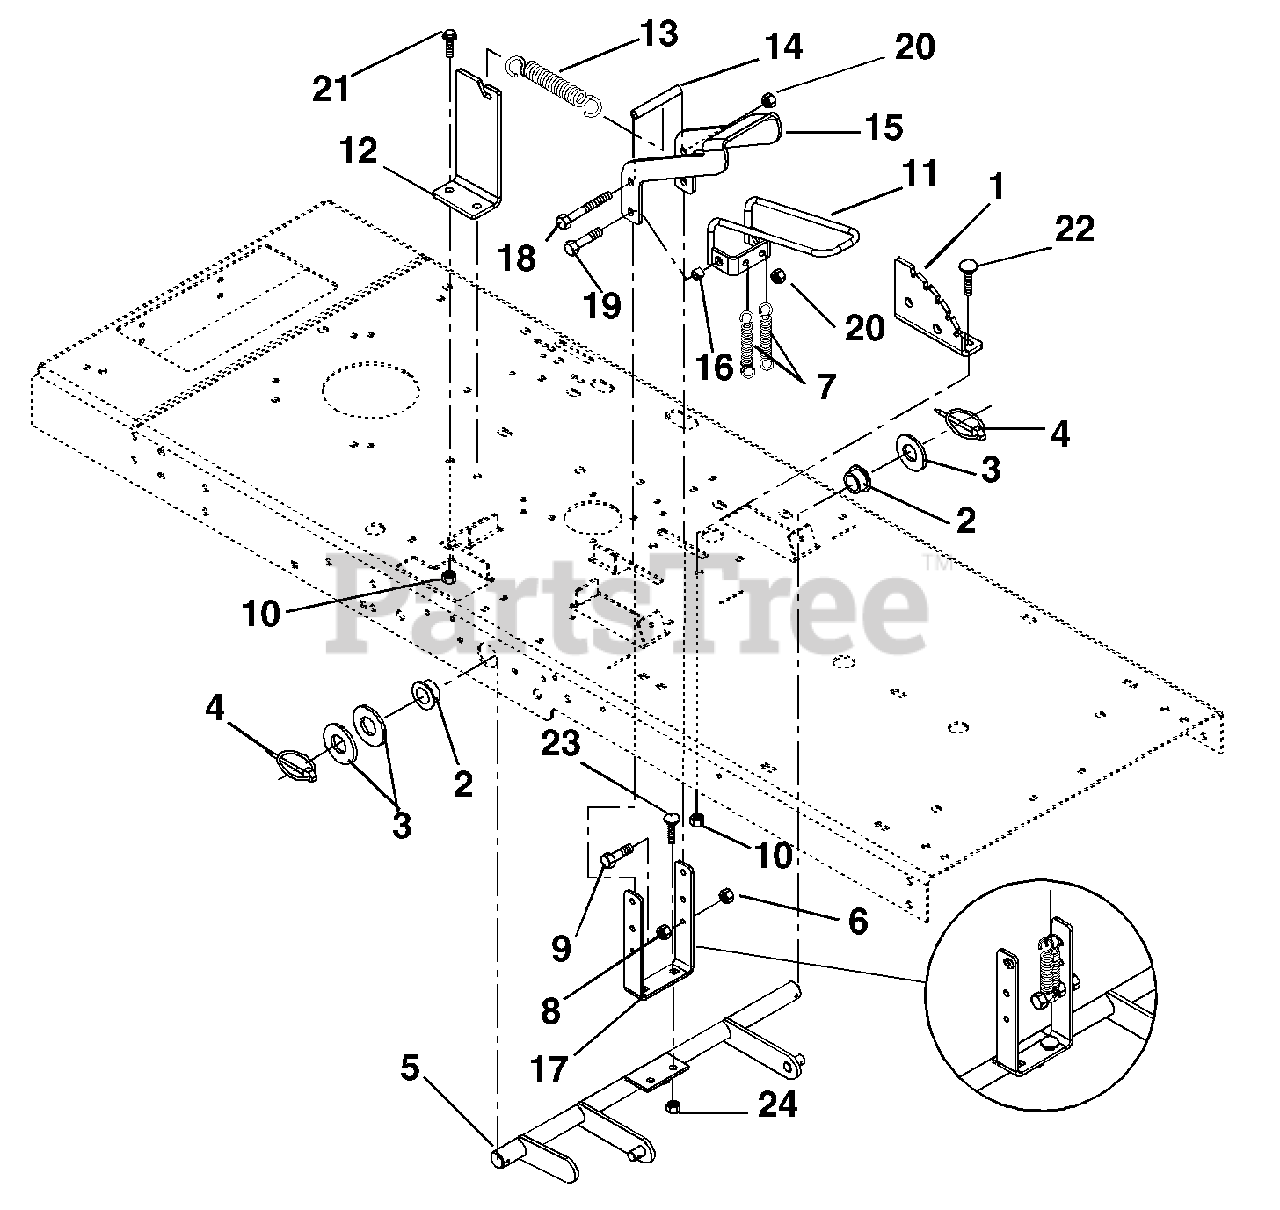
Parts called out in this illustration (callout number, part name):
1	DETENT, PLATE
2	BSHG-FLG1.020X1.385X.75X1.75NY
3	WSHR-FL-STL- 1.062X2.0X.134 YZ
4	PIN-KLIK .25X1.75
5	LIFT, WLDM'T
6	@NUT-LK-CTR .25-20 YWZC
7	SG-TENS .092X.69X1.75 WLD 54
8	@NUT-HEX .25-20 YWZC
9	@BLT-HEX .25-20X2.00 GR5 YWZC
10	@NUT-LK-TOP-FLG .38-16 YWZC
11	RELEASE WLDM'T
12	BRACKET, LIFT
13	SG-TENS .187X1.50X9.94 WLD 40
14	SPACER .328 X .462 X 3.14
15	HANDLE, COATED DECK LIFT
16	SPACER .328 X .462 X .410
17	BRACKET, HANDLE
18	@BLT-HEX .31-18X4.50 GR5 YWZC
19	@BLT-HEX .31-18X1.25 GR5 YWZC
20	@NUT-LK-NYL .312-18 YWZC
21	BLT-SERHFWH .38-16X.75 YWZC
22	@BLT-RDHDSQNK .38-16X.75 G5YZ
23	@BLT-RDHDSQNK .38-16X1.00 G5YZ
24	@NUT-LK-TOP-FLG .38-16 YWZC
